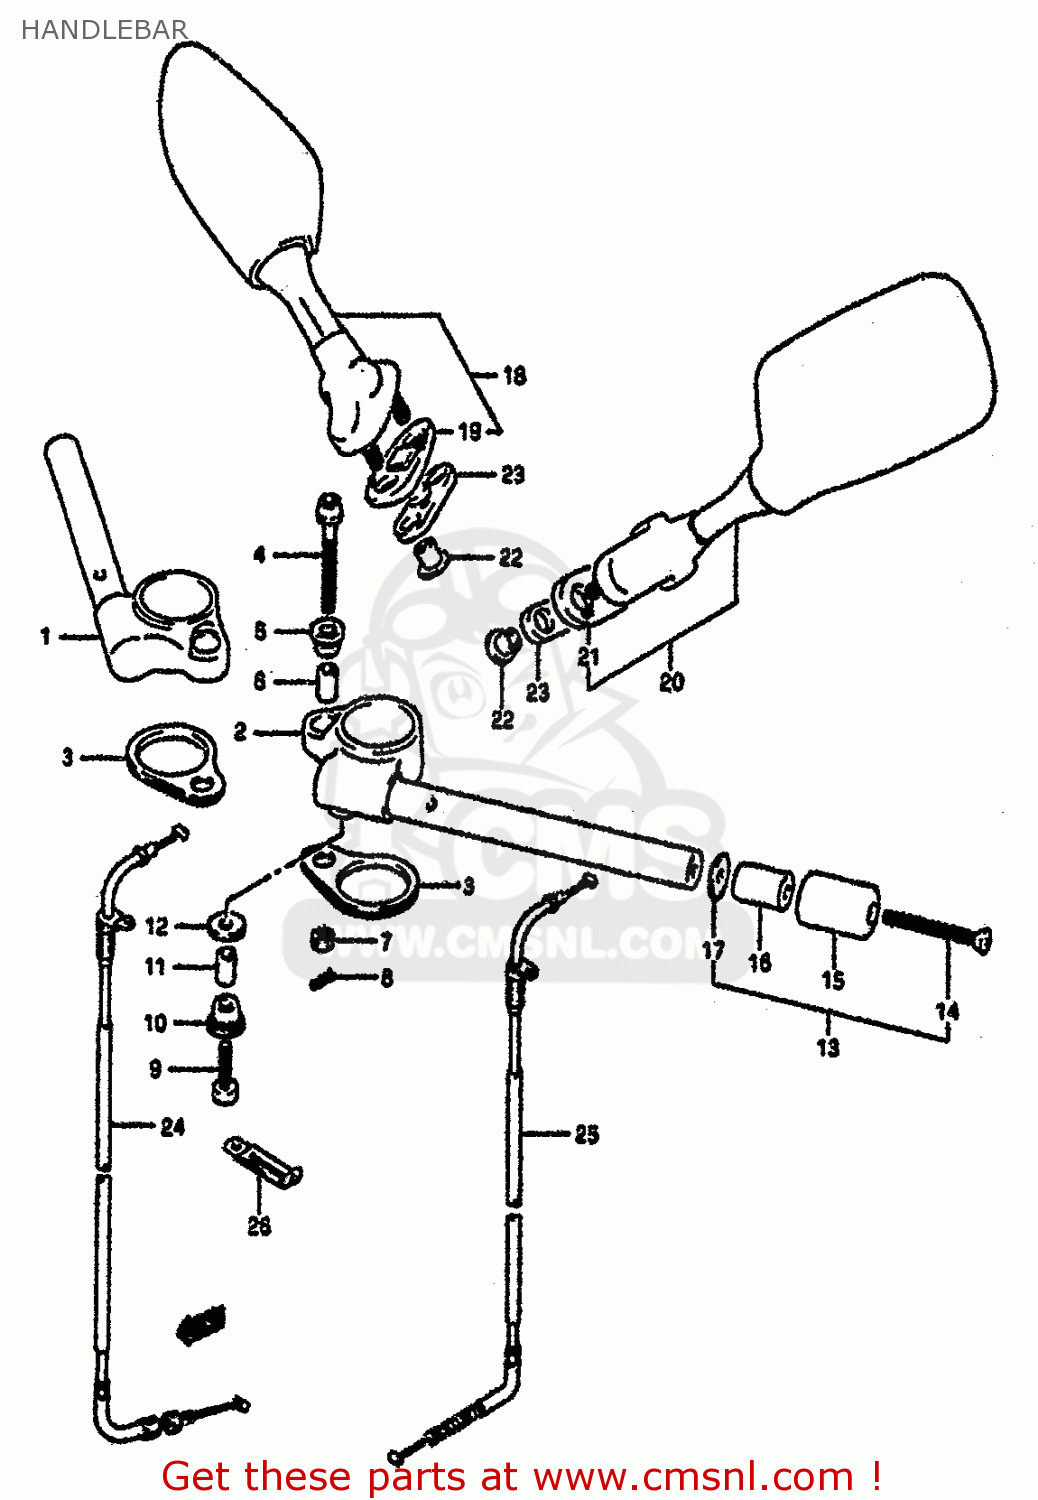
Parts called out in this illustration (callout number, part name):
1	HANDLEBAR,R
2	HANDLEBAR,L
3	CUSHION,HANDLEBAR
4	BOLT,HANDLEBAR
5	CUSHION,HANDLEBAR UPR
6	SPACER,HANDLEBAR
7	NUT 8MM
8	SNAP
9	BOLT, LH
10	CUSHION,HANDLEBAR UPR
11	SPACER,HANDLEBAR
12	CUSHION,HANDLEBAR SPACER
13	BALANCER SET,HANDLEBAR
14	SCREW (L:65)(SUS)
15	CAP,BALANCER
16	BALANCER,HANDLEBAR
17	SPACER,BALANCER
18	MIRROR ASSY,RR VIEW,R
19	GASKET,RR VIEW MIRROR,R (NAS)
20	MIRROR ASSY,RR VIEW,L
21	GASKET,RR VIEW MIRROR,L (NAS)
22	NUT,RR VIEW MIRROR
23	CUSHION,RR VIEW MIRRORR
24	CABLE ASSY,THROTTLE
25	CABLE,STARTER
26	CLAMP
